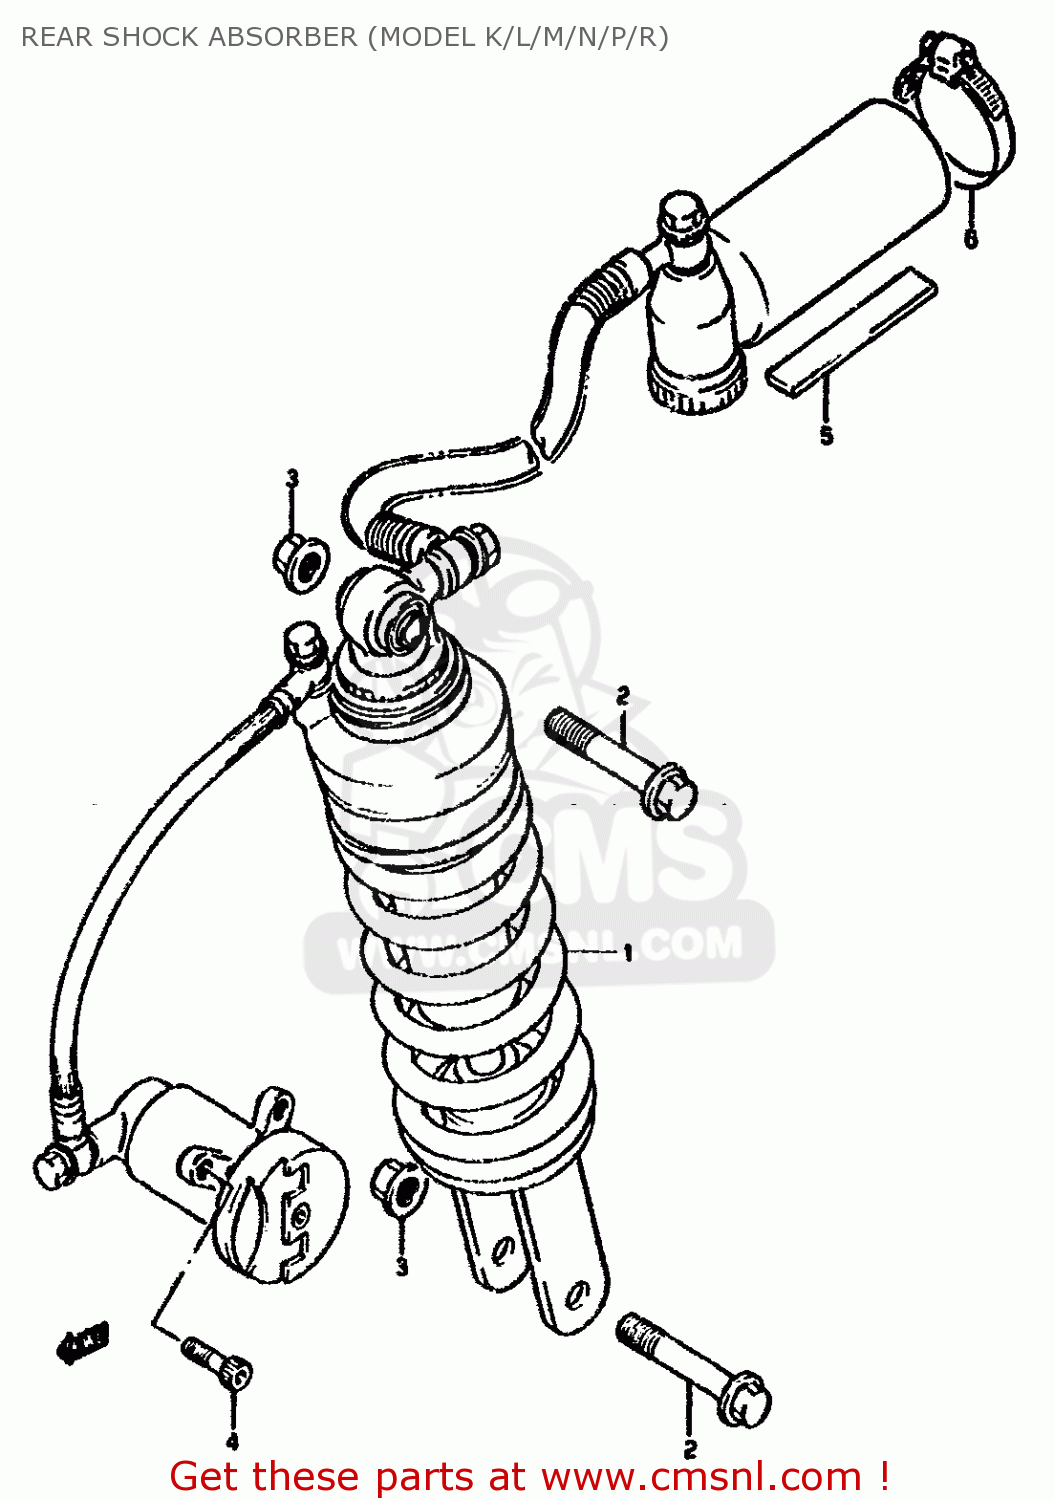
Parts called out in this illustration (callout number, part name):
1	ABSORBER ASSEMBLY,REAR SHOCK
2	BOLT(10X54)
3	NUT
4	BOLT
5	CUSHION, RESERVOIR TANK
6	CLAMP
